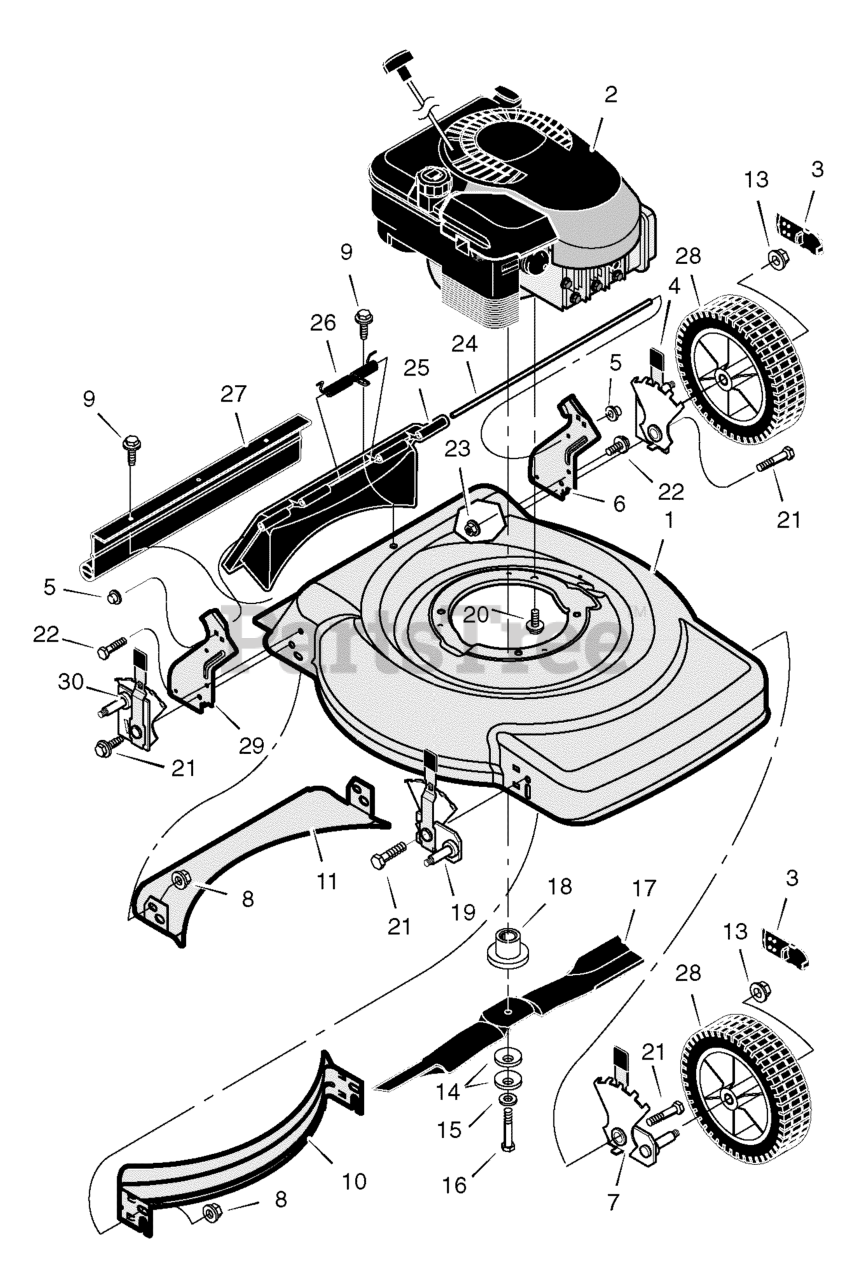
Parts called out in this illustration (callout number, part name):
1	Housing
2	Engine *
3	Cap, Hub (Optional)
4	Adjuster, Left Rear Height
5	Push On Cap
6	Bracket, Left Handle
7	Adjuster, Left Front Height
8	Nut, Flange
10	Baffle, Front
11	Baffle, Rear
13	Nut, Flange
14	Washer, Belleville
15	Washer
18	Adapter, Blade
19	Adjuster, Right Front Height
20	Bolt, Engine
22	Bolt
23	Nut, Flange
24	Rod, Pivot
25	Door, Rear (Black)
26	Spring
27	Guard, Rear
28	Wheel & Tire *
29	Bracket, Right Handle
30	Adjuster, Right Rear Height
